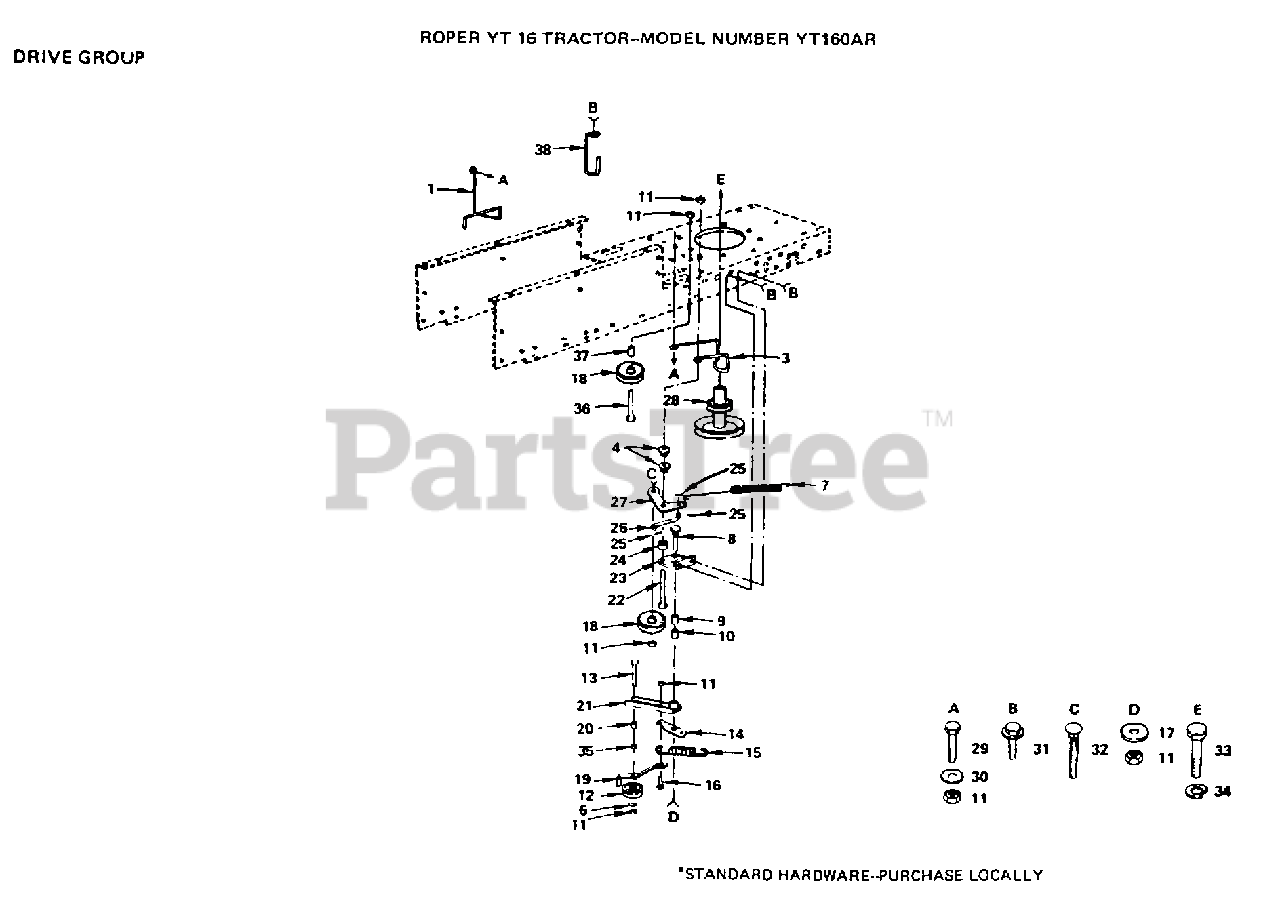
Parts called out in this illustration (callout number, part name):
1	GUIDE, BELT - ENGINE PULLEY
3	GUIDE BELT PLY LT
6	WASHER
7	SPRING CLUTCH LT
8	BOLT
12	IDLER.FLAT.GTV
13	BOLT
15	SPRING EXT LT
16	BOLT
17	WASHER
18	IDLER-FLAT LT
21	ARM IDLER ASSY LT
23	BRACKET SUPT LT
24	SPACER LT
25	COTTER PIN
26	LINK BELLCRANK
29	BOLT
30	WASHER
31	SCREW
32	BOLT
34	LOCKWASHER
35	NUT.HEX.3/8-16UNC
36	BOLT
37	SPACER SPLIT LTV
